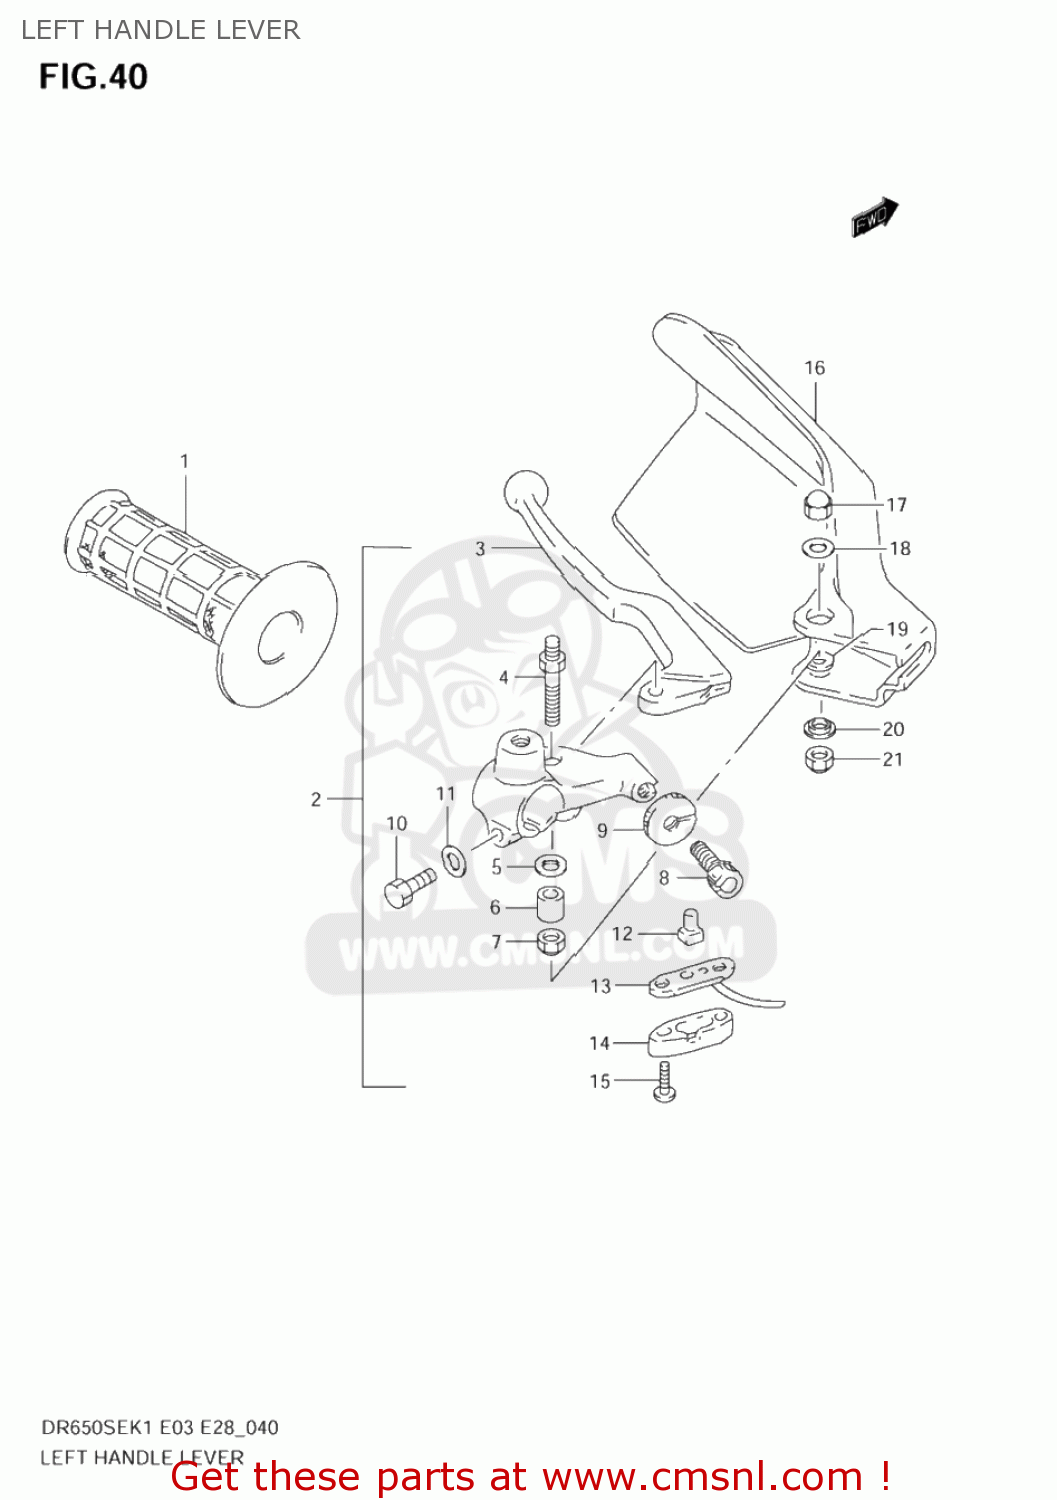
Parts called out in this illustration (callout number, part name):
1	GRIP,L
2	LEVER ASSEMBLY,CLUTCH
3	LEVER,CLUTCH
4	BOLT,CLUTCH LEVER PIVOT
5	WASHER
6	SPACER,LEVER SET
7	NUT
8	ADJUSTER,CABLE
9	NUT,CABLE ADJUSTER LOCK
10	BOLT
11	WASHER
12	CONTACT,SWITCH
13	HARNESS ASSY,WIRE
14	COVER,FR BK TERMINAL BASE
15	SCREW
16	COVER,KNUCKLE,LEFT
17	NUT
18	WASHER(6.5X20X1.6)
19	WASHER(6.5X16X1.2)
20	WASHER
21	NUT 6MM
